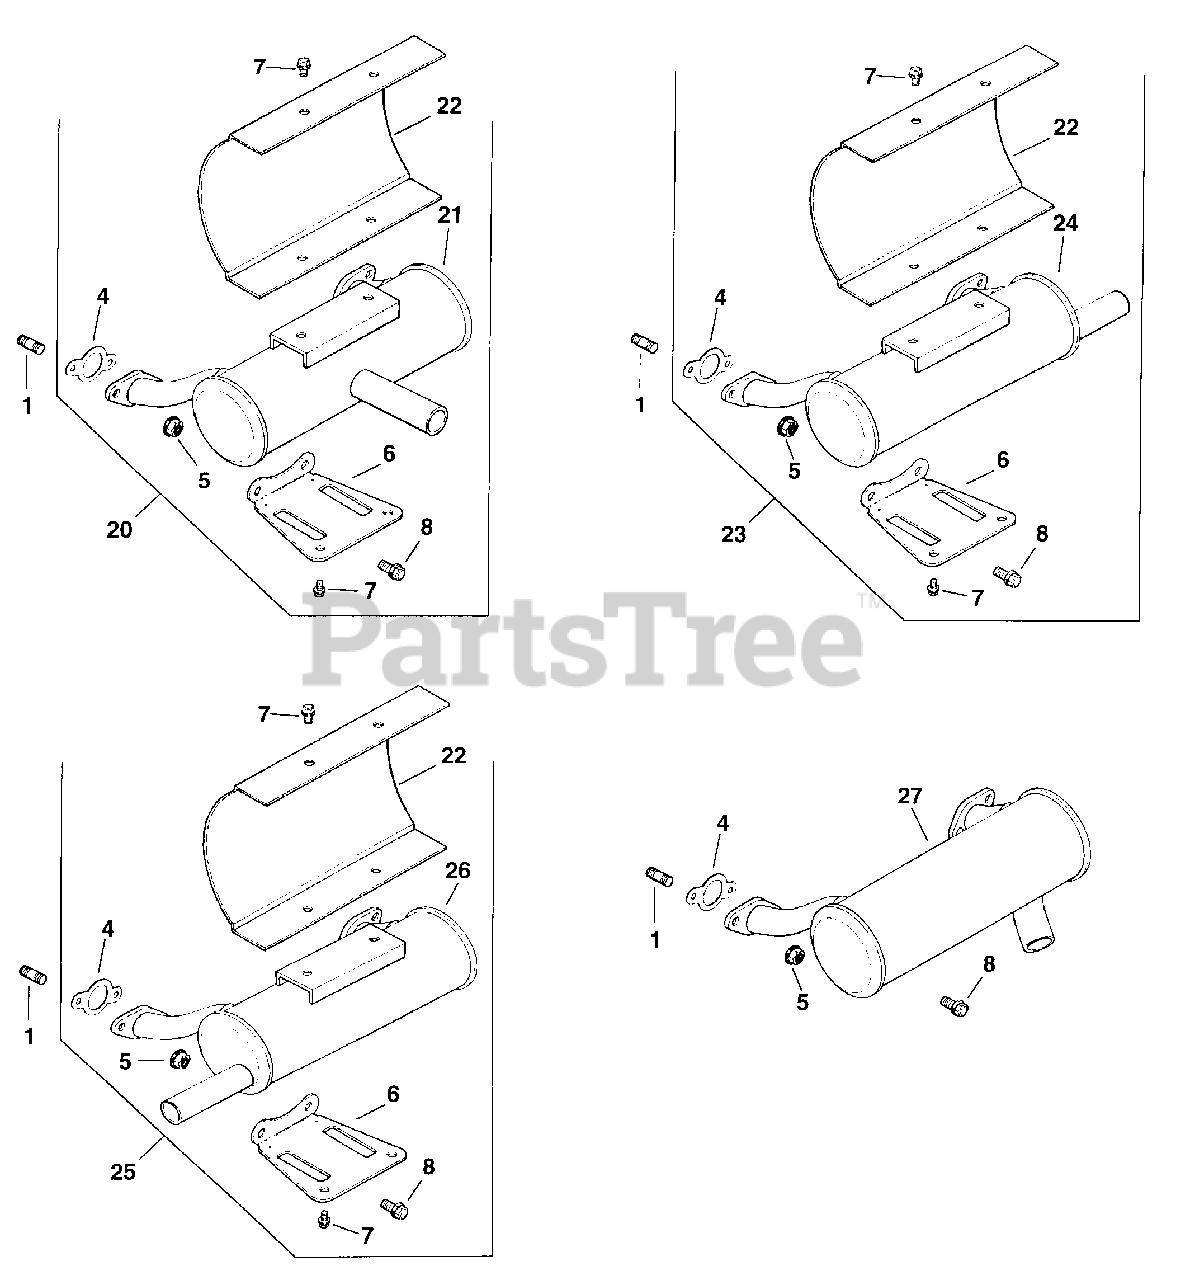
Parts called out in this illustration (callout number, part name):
1	STUD - USE M-829033
5	NUT - USE M-841080
8	Screw, hex. flange M8x1.25x20
27	MUFFLER USE 24 068 147-S
